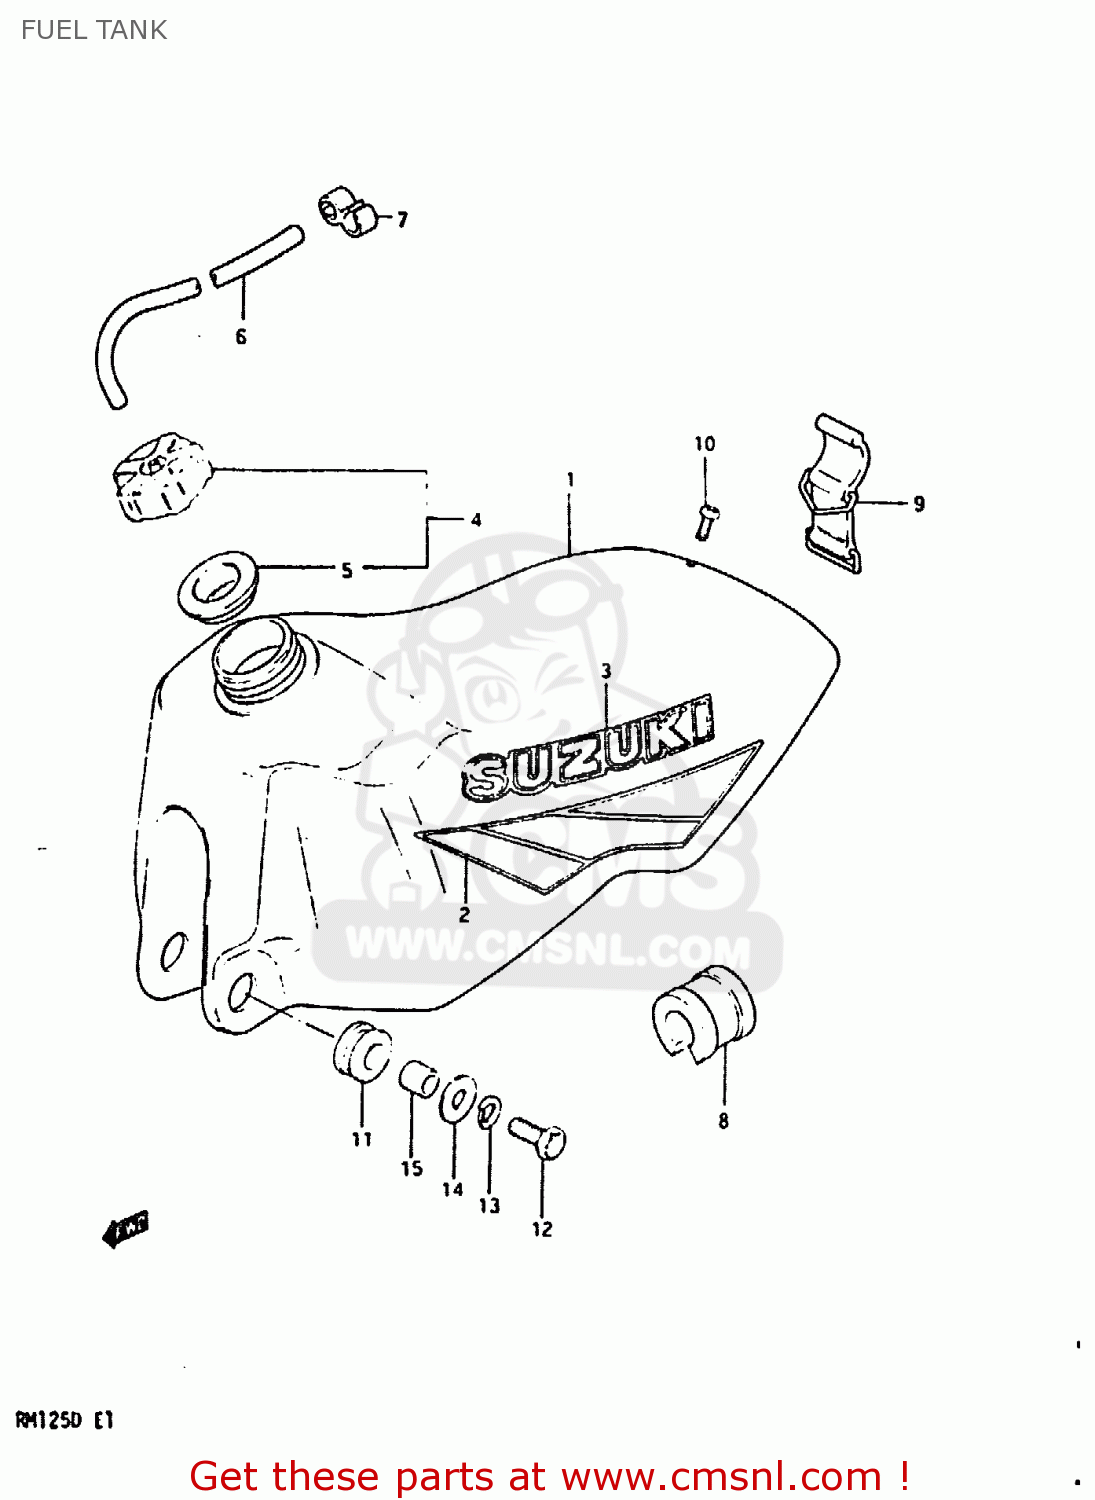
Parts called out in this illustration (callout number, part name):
1	TANK ASSEMBLY,FUEL
2	TAPE SET,FUEL TANK
3	EMBLEM
4	CAP SET,FUEL TANK
5	GASKET,FUEL TANK CAP (NAS)
6	HOSE
7	CLAMP,BREATHER HOSE
8	CUSHION,FUEL TANK UPR
9	BAND
10	SCREW (6X15)
11	CUSHION
12	BOLT (8X30)
13	LOCK WASHER
14	WASHER (8.5X26X1.2)
15	SPACER (8.8X12X13.5)
